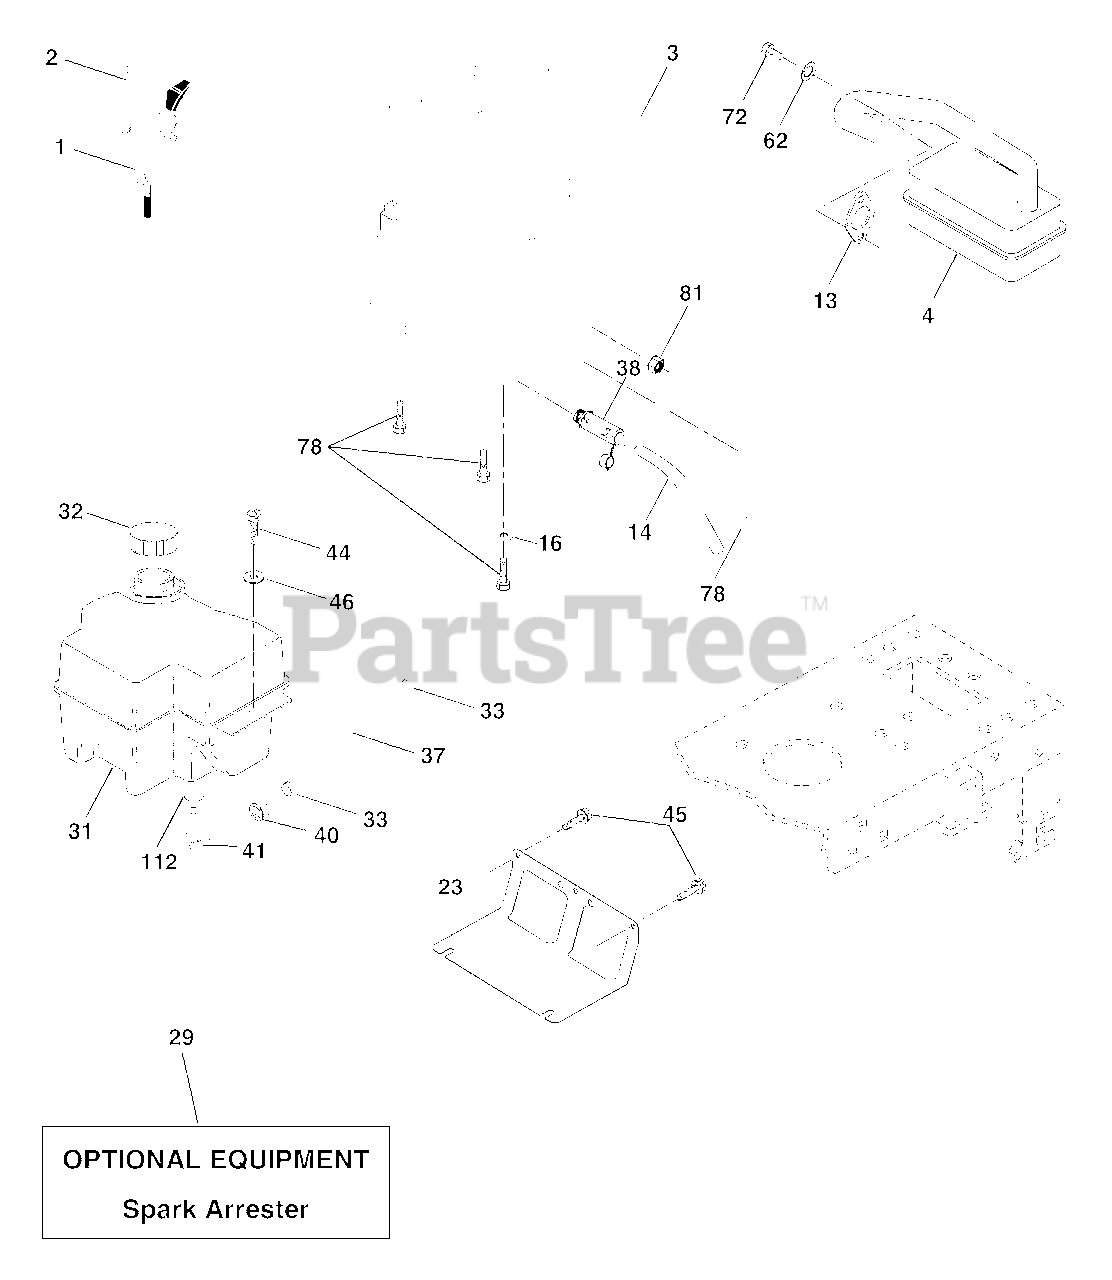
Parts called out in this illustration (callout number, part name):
1	Control Th/ch Flag Dom.
2	Screw Hex Thd Cut 1/4-20x1/2
13	Gasket
14	Tube Drain Oil Easy
16	Washer Lock Ext Tooth 3/8
23	Shield BRN/DBR Guard
29	Kit Spark Arrestor (Flat Scrn)
32	Cap Asm Fuel W/sym Vented
33	Clamp Hose Black
37	Line Fuel
38	Plug Drain Oil Easy
40	Bushing Snap Nyl Black Fuel Line
41	Stem Tank Fuel
44	Screw Hex Wsh Thdrol 1/4-20 x 3/4
45	Screw Hex Wsh Thdrol 3/8-16 x 3/4
46	Washer 9/32 x 7/8 x 16 Ga.
62	Washer Lock Hvy Hlcl Spr. 5/16
72	Screw Hex Hd Cap 5/16-18 x 3/4
78	Screw 3/8-16 x 1-1/4
81	Nut Keps Hex 1/4-20 Unc
112	Bushing
